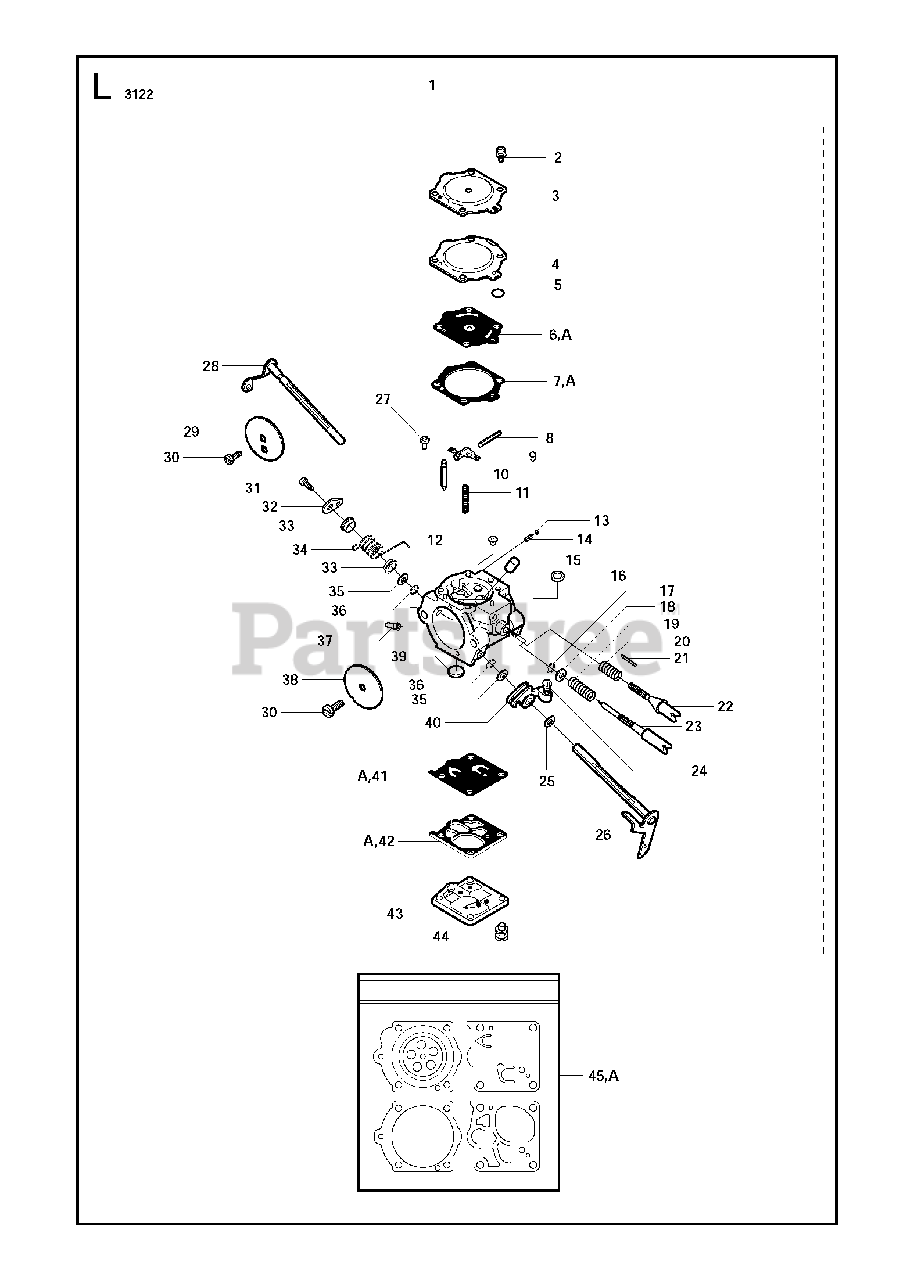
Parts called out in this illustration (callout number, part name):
1	CARBURETTORWalbro WG-9A
6	DIAPHRAGM ASSYKit 45
7	GASKETKit 45
8	PIN-METERING LEVER
21	PIN THROTTLE STOP
22	SCREW IDLE SPEED
23	NEEDLE IDLE SPEED
31	SCREW PAN HD(M2.5X5)
34	SPRING THROTT RETURN
38	VALVE THROTTLE
41	DIAPHRAGM PUMPKit 45
42	GASKETKit 45
